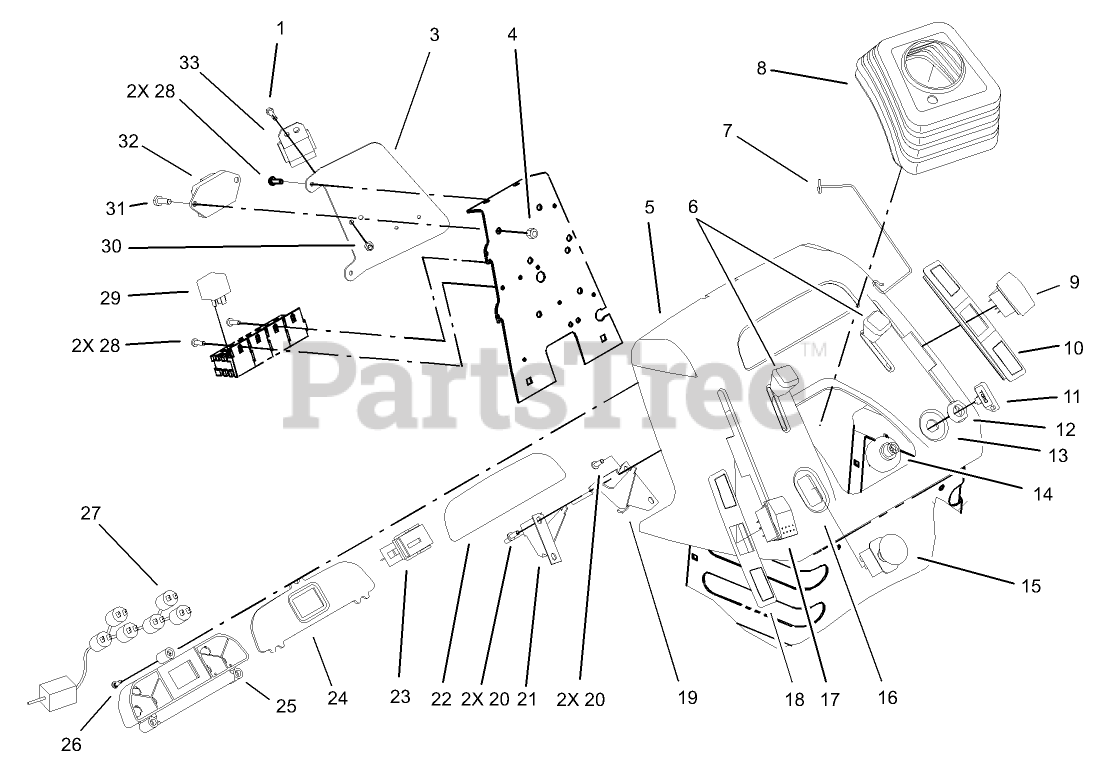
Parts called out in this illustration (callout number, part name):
3	PANEL-SUPPORT, AUX
4	NUT-LOCK, NI
7	CLIP-BOOT
8	BOOT-STEERING
9	SWITCH-CRUISE
10	COVER-SLOT, RH
11	KEY-IGNITION
13	DECAL-DASH
13	DECAL-THROTTLE, IGNITION
14	SWITCH-IGNITION
15	SWITCH-PTO,ON-ON-NONE
16	DECAL-DASH, PTO/CHOKE
16	DECAL-PTO / CHOKE
17	SWITCH
18	COVER-LIFT
19	CONTROL-THROTTLE (TWIN)
21	CONTROL-CHOKE (TWIN)
22	DECAL - DASH LENS
23	HOURMETER
24	LENS-DASH
25	HOUSING-LIGHT
26	SCREW
27	HARNESS-6 LAMP
28	SCREW-PPHTF
29	RELAY
30	NUT-LOCK, NI
31	SCREW-HH
32	MODULE-CLUTCH
33	MODULE-LOW VOLTAGE
